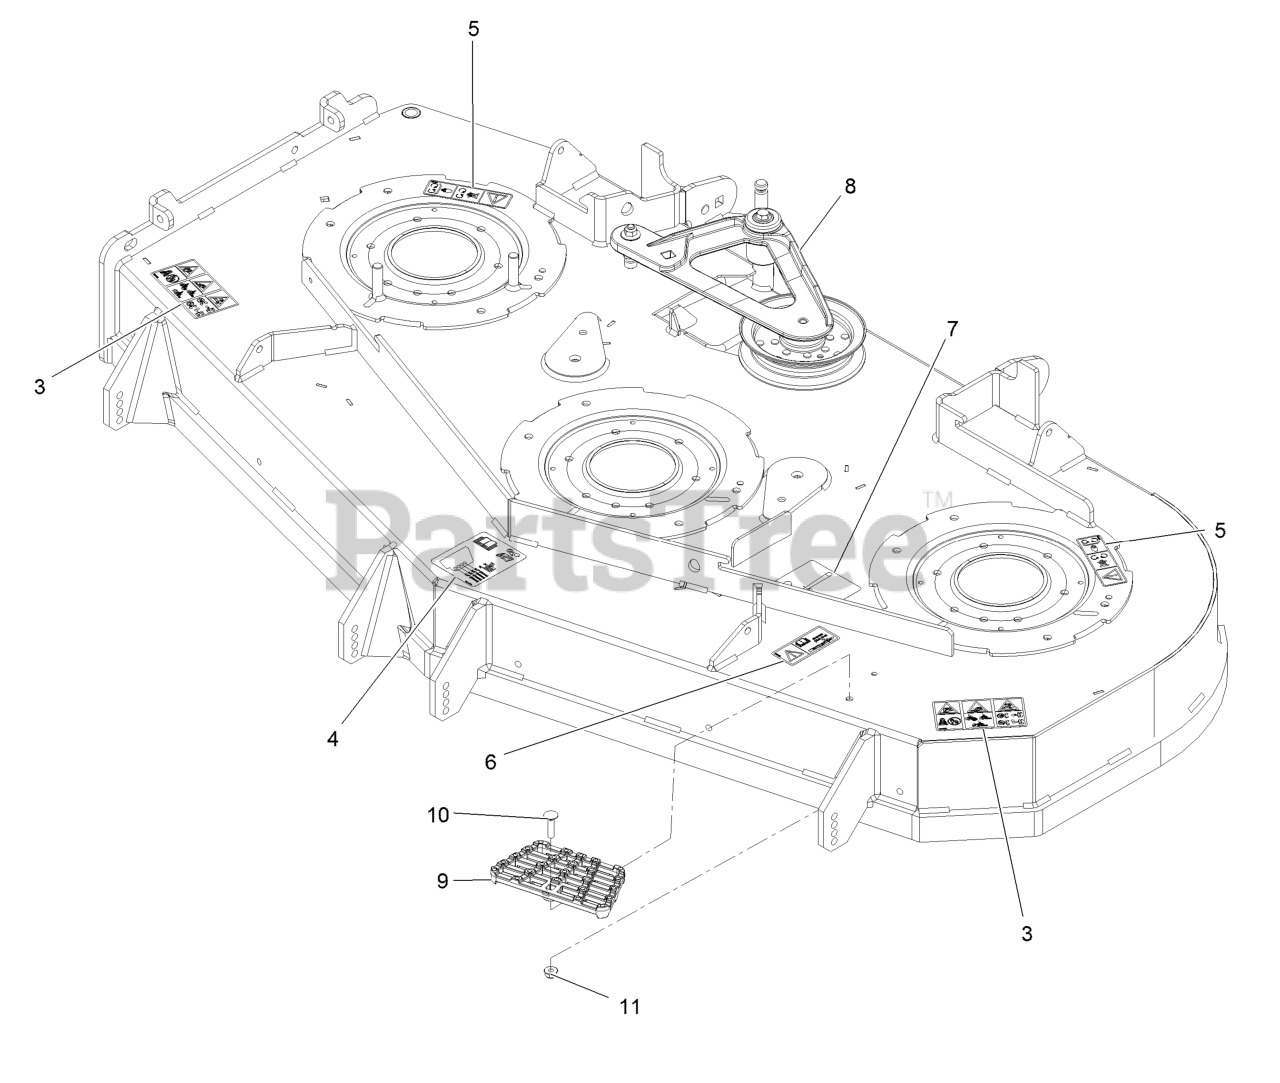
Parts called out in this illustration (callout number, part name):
3	Decal-Danger Thrown Objects
4	Decal-Roller, Anti-Scalp
5	Decal-Missing, Cover
6	Decal-Bolt Torque
7	Decal-Belt Routing
8	Deck Idler ASM
9	Step-Deck
10	Bolt-Carriage 5/16-18 X 1 1/4
11	Nut-Nyloc 5/16-18 Flg
